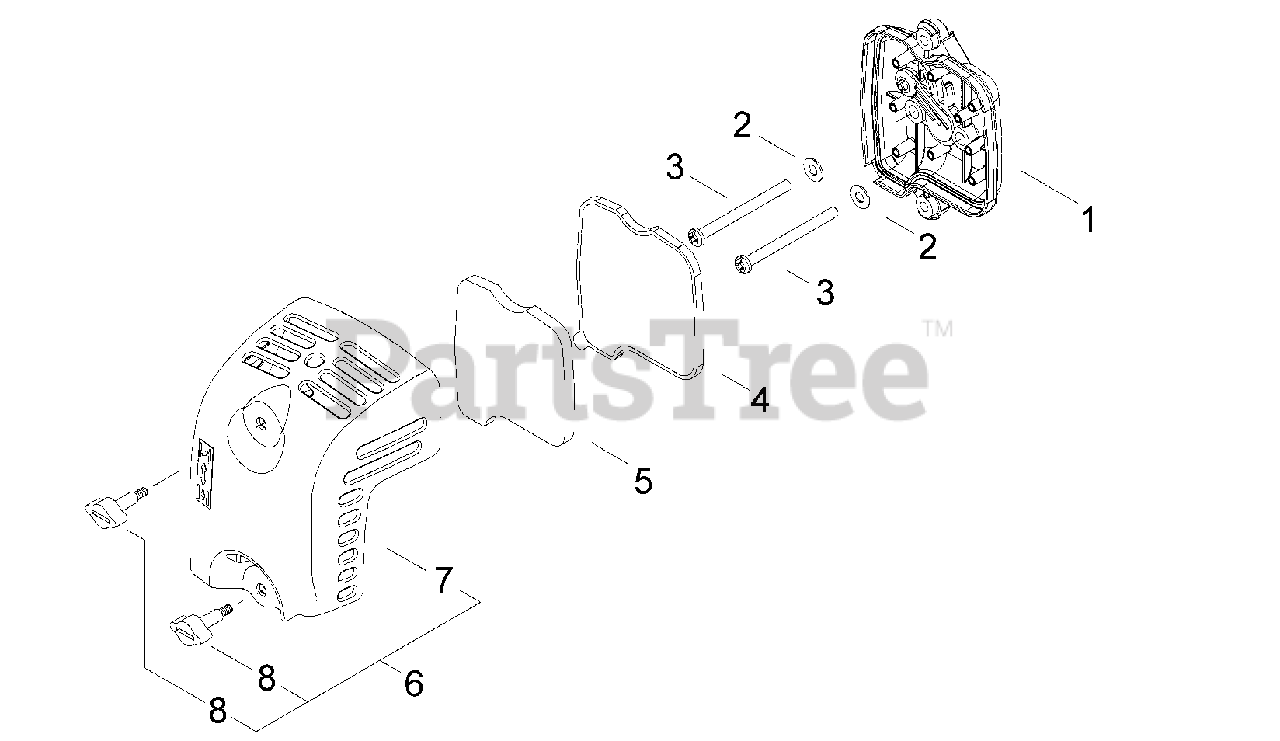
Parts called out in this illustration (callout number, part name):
1	CASE ASSY, AIR FILTER
2	WASHER 5 MM
3	SCREW M5×60
4	FILTER, AIR
5	PRE-FILTER, FOAM
6	COVER ASSY, AIR FILTER
7	COVER, AIR FILTER
8	THUMBSCREW M5
